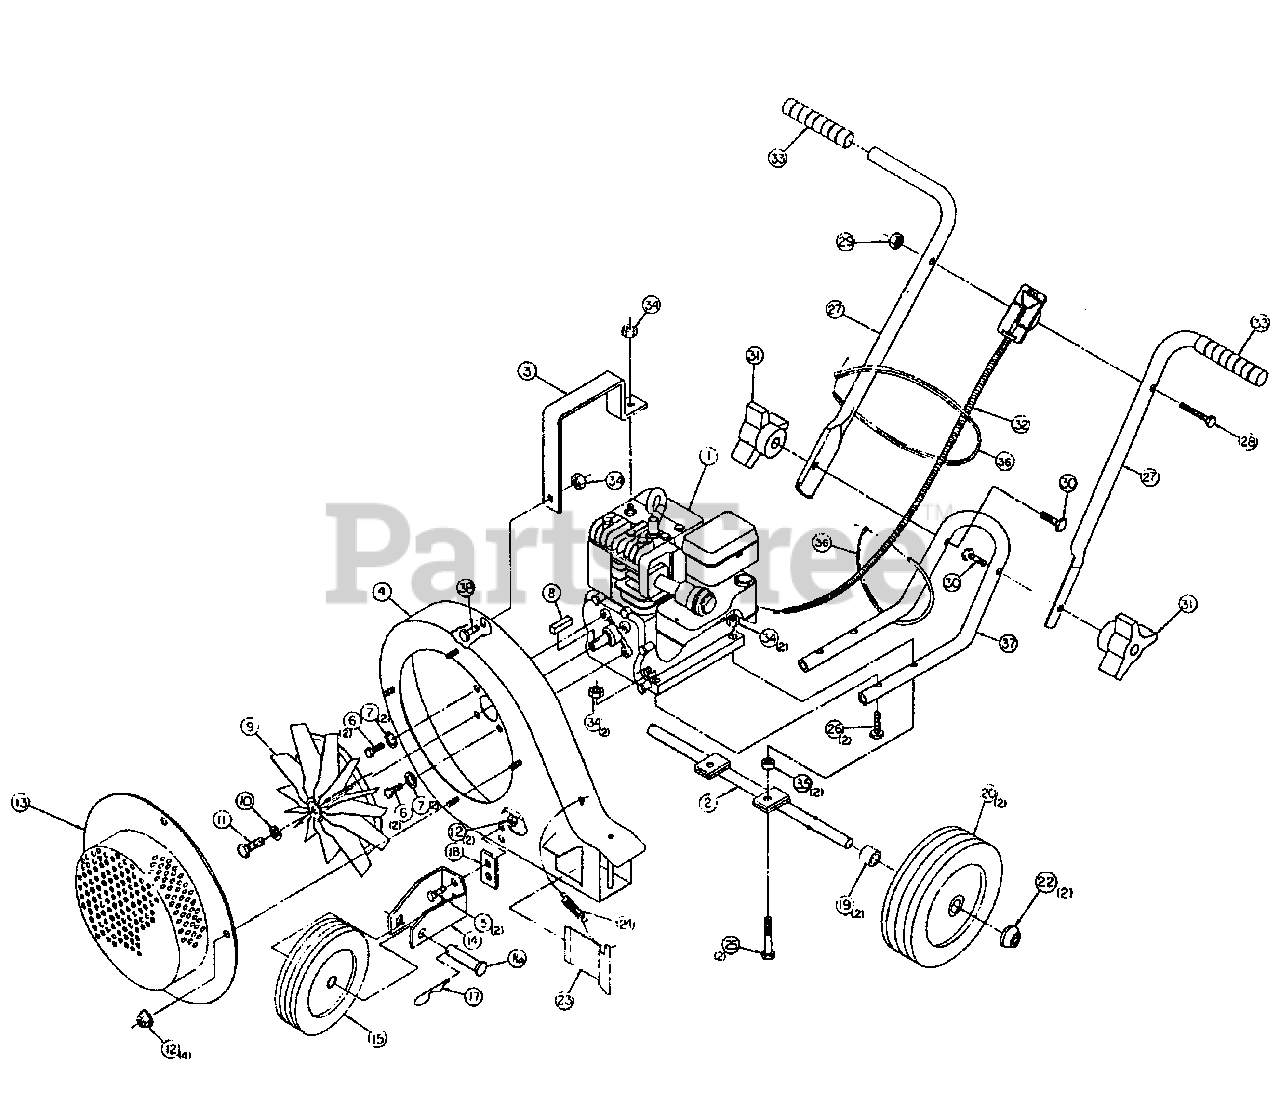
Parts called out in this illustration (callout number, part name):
1	Engine,
2	Axle Assembly
3	Lifting Handle
4	Housing Assembly
5	5/16-18 x 3/4" HHCS
6	5/16-24 x 3/4" HHCS
7	5/16" Split Lockwasher
8	1/4" x 1/4" x 2" Shaft Key
9	Impeller Assembly
10	WASHER, 3/8 Split Lock
11	3/8-24 x 1" Whizlock Screw
12	5/16-18 Whizlock Nut
13	Impeller Housing Cover
14	Wheel Bracket
15	Front Wheel 5 x 1.25
16	Clevis Pin 1/2" DIA x 2" LG
17	3/32" Hair Cotter Pin
18	Wheel Bracket Spacer
20	Main Wheel
22	Push Nut Cap
23	Diverter
25	5/16-18 x 2 3/4" HHCS
26	5/16-18 x 2 1/4" HHCS
27	Upper Handle
28	1/4-20 x 2 3/4" HHCS
29	1/4-20 Nylock Nut
30	5/16-18 x 1-1/2" HHCS
31	Locking Knob
32	Throttle Control
33	Handle Grip
34	5/16-18 Gripco Locknut
35	Spacer, Engine
36	Ty-Wrap
37	Lower Handle
38	5/16-18 x 5/8" HHCS, GR5
